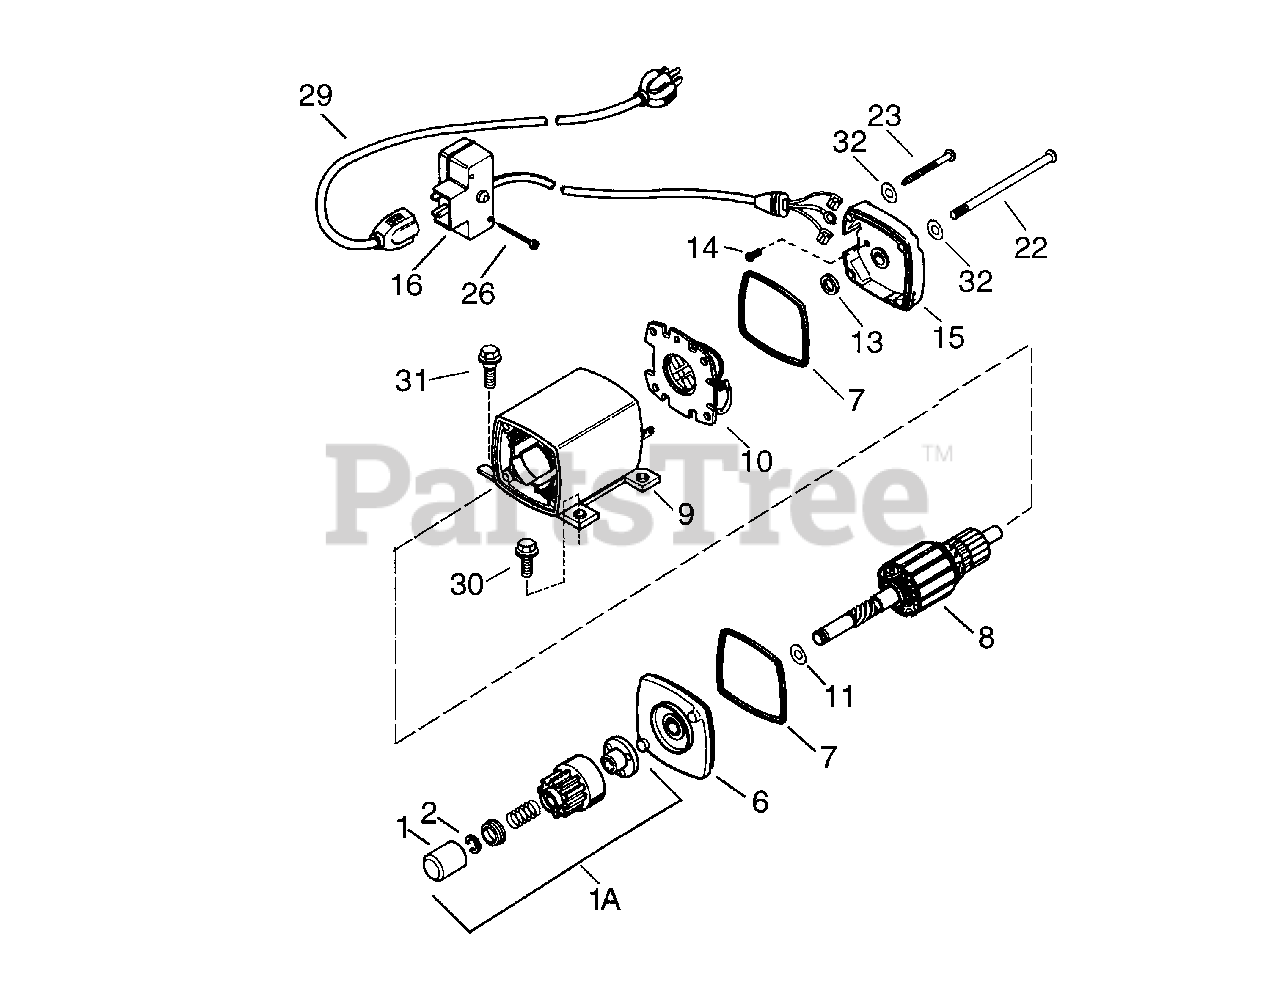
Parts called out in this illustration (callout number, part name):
1	Dust Cover Fits Starters built throug h June 2005
1	Dust Cover Fits Starters built AFTER June 2005
1A	Drive Kit (Incl. 1 & 2)
2	Retainer Ring
6	Drive End Cap Ass'y (Incl. 7)
7	"O" Ring
8	Armature
9	Housing Assembly
10	Brush Card Assembly
13	Thrust Washer
14	Ground Screw
15	Commutator End Cap Ass'y (Incl. 7)
16	Switch Box
22	Case Bolt
23	Ground Screw
26	Screw, 6-32 X 2-1/2" Use with 2" thic k switch box
26	Screw, 12-16 x 5/8"
26	Screw, 6-20 x 2" Use with 1-9/16" thi ck switc h box
29	Extension Cord (10'6")
30	Screw, T-30, 1/4-20 x 1/2"
31	Screw, 1/4-20 x 1/2" (Upper Mounting Screws for 120-Volt Electric Starter Motor)
32	Washer (NOTE: All three (3) 37066 w ashers must be replaced each time in ternal parts are serviced.)
